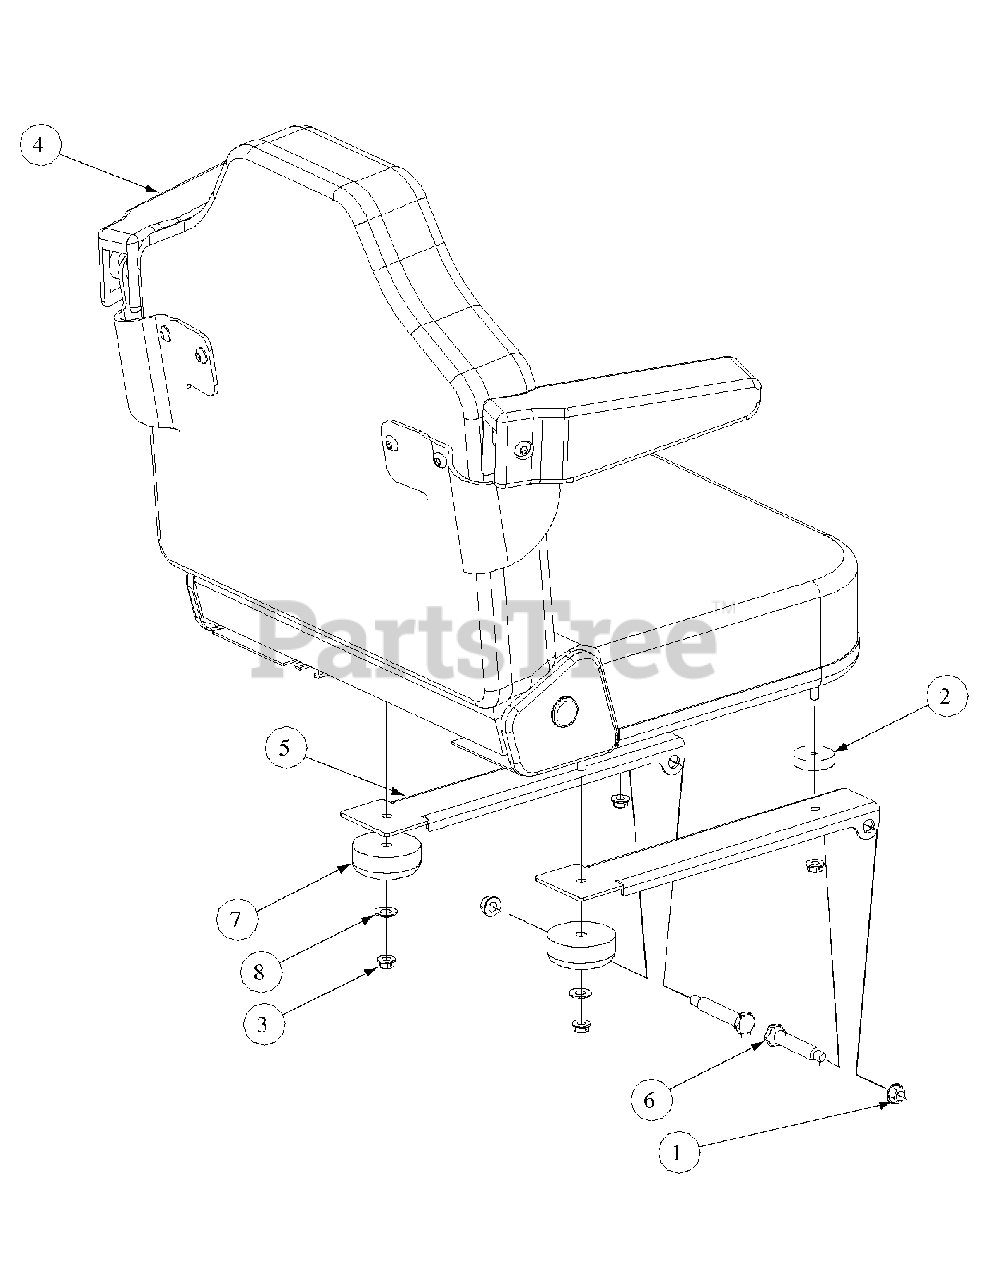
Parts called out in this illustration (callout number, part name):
1	Nut, Hex 3/8-16 Flange Lock
2	Spacer, 0.406 ID x 1.00 OD x .38
3	Lock Nut, Hex Flange, 5/16-18
4	Adjustable Seat, Black embossed, Forward Fold
5	Mounting Bracket, Seat
6	Shoulder Screw, .50x2.345, 3/8-16
7	Grommet, 2.5 OD x 1.0 Long
8	Washer
